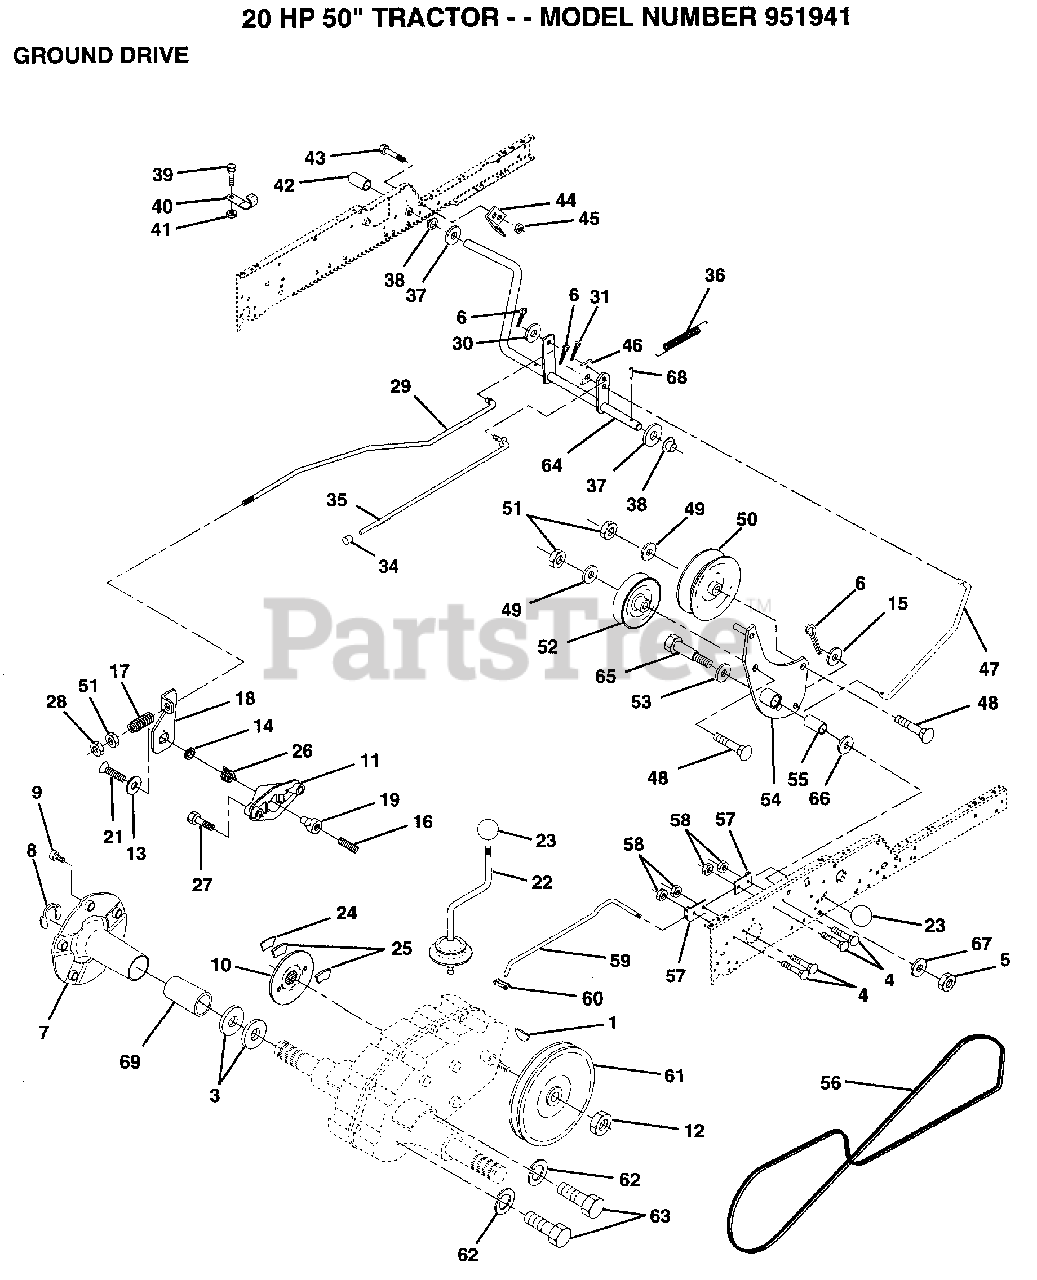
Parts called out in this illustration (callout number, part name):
3	WASHER T
4	BOLT
6	COTTER PIN
8	KLIP RING
9	BOLT.HUB.WHL.REAR
11	YOKE BRAKE DISC
12	NUT STD
13	WASHER SPECIAL
14	BUSHING LEVER BKT
15	WASHER
16	SCREW FLT 1/4X28
17	"SPRING,ROD BRAKE"
18	LEVER BRAKE GT
19	CAM BRAKE DISC GT
21	SCREW SET 1/4-20
22	GEAR SHFT LVR T
23	KNOB
24	SUPPORT PUCK BRKE
25	PUCK BRAKE TOP
26	SPRING RET BRAKE
27	SCREW HX WASH
28	NUT
29	ROD BRAKE ZINC GT
30	WASHER
34	PLUNGER CAP T
35	ROD BRAKE PART GT
37	WASHER
38	NYLINER T
39	SCREW
40	ACT-SWITCH T
42	PEDAL COVER T
43	BOLT LT
44	BRKT SWITCH GT
45	NUT
46	RETAINER SPRING
47	ROD.CLUTCH
48	BOLT
49	WASHER
50	FLAT IDLER PULLEY
51	NUT
52	PULLEY.IDLER.V.GR
53	WASHER T
54	ARM.ASM.IDLER.CLU
55	"LY, BEARING"
56	BELTV.GR.DR.83.
57	ROD BRACKET GT
58	NUT
59	ROD SHIFT HI LO
60	CONNECTING LINK
62	LOCKWASHER
63	BOLT
65	AXLE BOLT
66	WASHER.HARD.BLADE
67	WASHER
68	ROLL PIN STD
69	"COVER, HUB"
